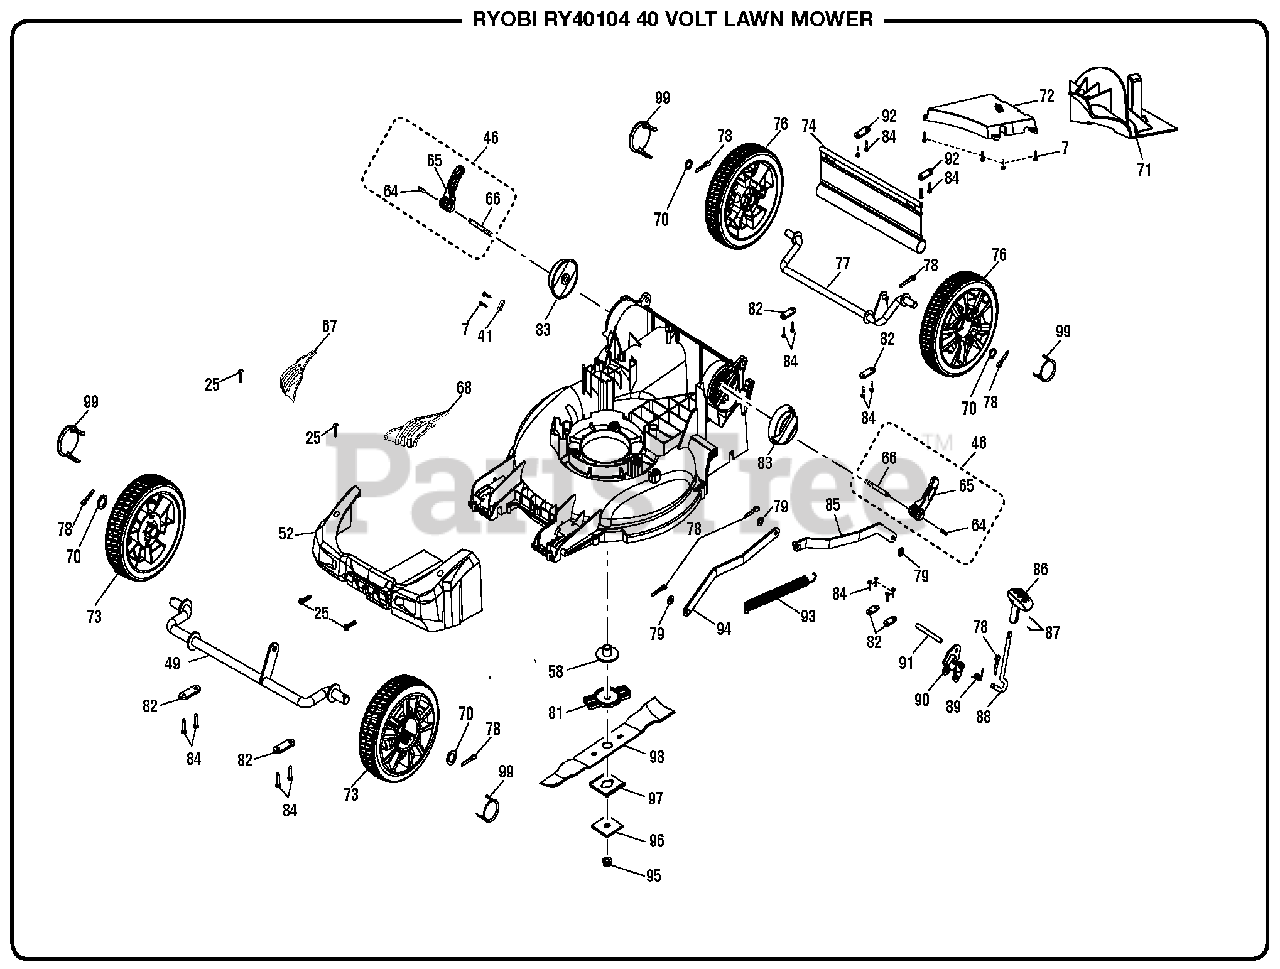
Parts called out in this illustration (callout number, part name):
7	Screw (M4 x 16, T20 Torx Hd.)
25	Screw (M3.5 x 20 mm, T20 Torx Pan Hd.)
41	Cord Clamp
46	Handle Lock Assembly
49	Front Wheel Axle
58	Motor Shaft Bushing
64	Spring Pin
66	Quick Lock Press
67	Grass Protector (Right)
68	Grass Protector (Left)
70	Washer (OD20 x ID13 x 1t)
71	Mulching Plug
72	Rear Cover
73	Front Wheel w/Bearing & Cap
74	Rear Skirt
76	Rear Wheel w/Bearing & Cap
77	Rear Wheel Axle
78	Cotter Pindia (2.5)
79	Washer (OD18 x ID8.4 x 1t)
81	Blade Holder
82	Axle Pressure Plate
83	Base (Lock Handle)
84	Screw (M4 x 18 mm, T20 Torx Pan Hd.)
85	Rear Lift Rod
86	Height Adjustment Handle
87	Screw (M3 x 9 mm, Flat Hd.)
88	Height Adjustment Lever
89	Torsion Spring (Height Adjustment)
90	Height Adjustment Bracket
91	Axle (Height Adjustment)
92	Pressure Plate (Height Adjustment)
93	Retention Spring
94	Front Lift Rod
95	Blade Nut (M10 x 1.25, Hex Flange Hd.)
96	Blade Retainer
98	Blade (16 in.)
99	Wheel Cover
